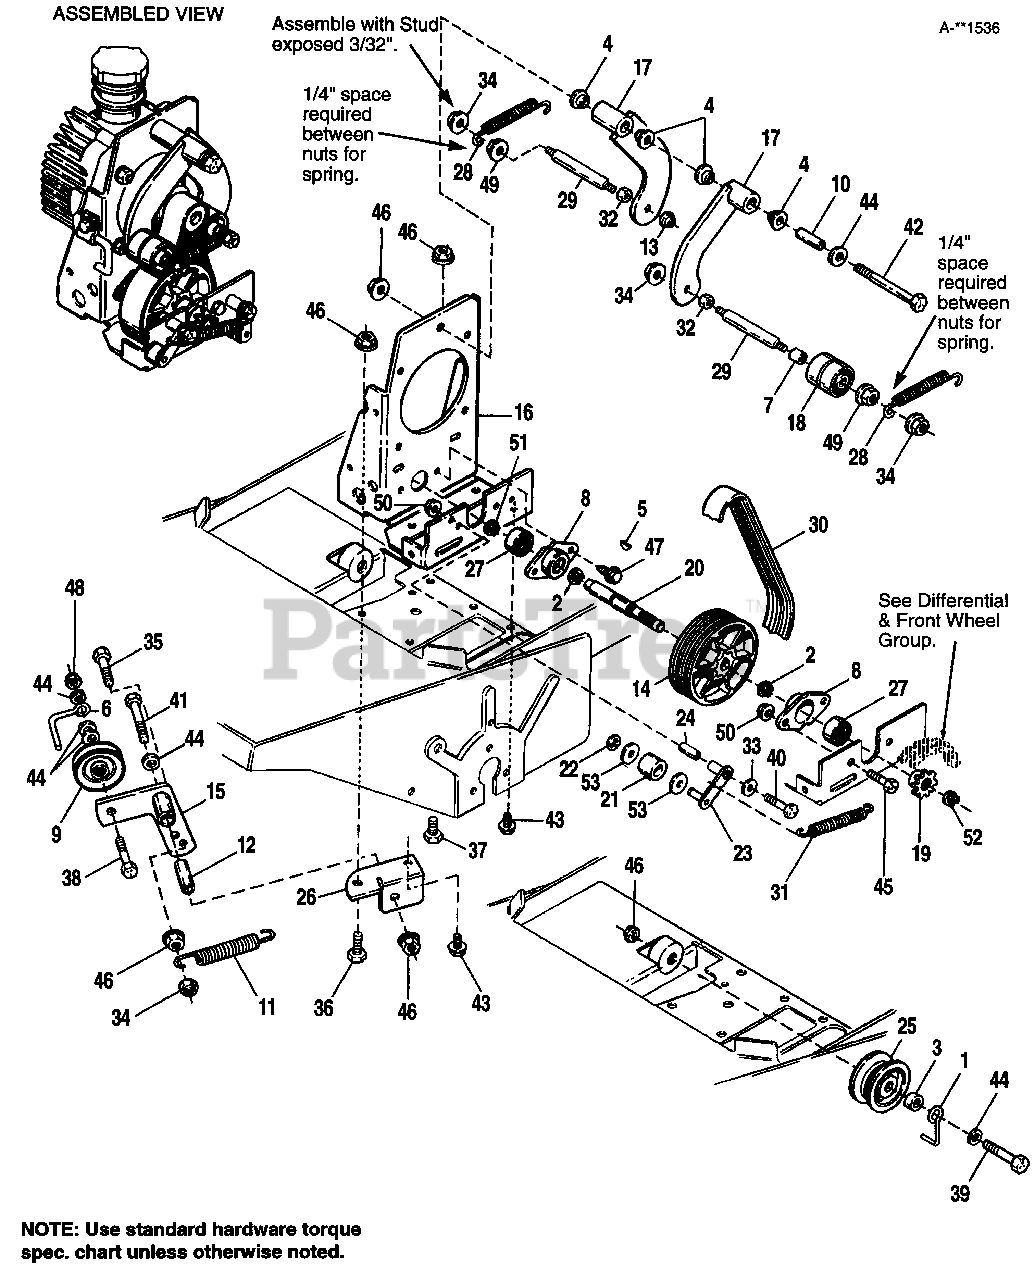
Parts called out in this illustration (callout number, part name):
2	RING, Retaining
5	KEY, Woodruff
8	RETAINER, Bearing
9	PULLEY, Idler
10	TUBE, Pivot
14	PULLEY, Drive
15	CLUTCH ARM ASSY.
16	BRACKET, Pump Mount
17	IDLER ARM ASSY.
18	PULLEY, Idler
19	SPROCKET, Drive (9 Teeth)
21	ROLLER, Chain
22	KLIP RING, Retaining
23	CONTROL ARM ASSY.
24	SPACER, Control Arm Assy.
25	PULLEY ASSY., Idler
26	BRACKET, Clutch Arm
27	BEARING Ball
28	SPRING, Tension, 4"
29	STUD, 3/8-16 X 4-1/2
30	BELT, Drive, Poly "V"
31	SPRING,Tension, Idler Assy.
32	NUT, Jam, 3/8-16
33	WASHER, Plain, 5/16
34	NUT, Hex, ESNA, Lock, 3/8-16
35	CAPSCREW, Hex, 3/8-16 x 1-1/4
36	CAPSCREW, Hex, 3/8-16 x 1
37	CAPSCREW, Hex, 3/8-16 x 3/4
38	CAPSCREW, Hex, 3/8-16 x 1-3/4
39	CAPSCREW, Hex Hd., 3/8-16 x 2-3/4
40	CAPSCREW, Hex Head 5/16-18 x 2 G5
41	CAPSCREW, Hex, Hd., 3/8-16 x 2-1/4
42	CAPSCREW, Hex, 3/8-16 x 4
43	SCREW, Hex, Taptite, 5/16-18 x 1/2
44	WASHER, 3/8
45	CAPSCREW, Hex, 5/16-18 x 5/8
46	NUT, Hex, Flange, Lock, 3/8-16
47	SCREW, Taptite, 5/16-18 x 3/8
48	NUT, Centerlock 3/8-16
49	NUT, Hex, Whiz, 3/8-16
50	NUT, Hex, Whizlock, 5/16-18
51	RING, Retaining
52	RING, Retaining
